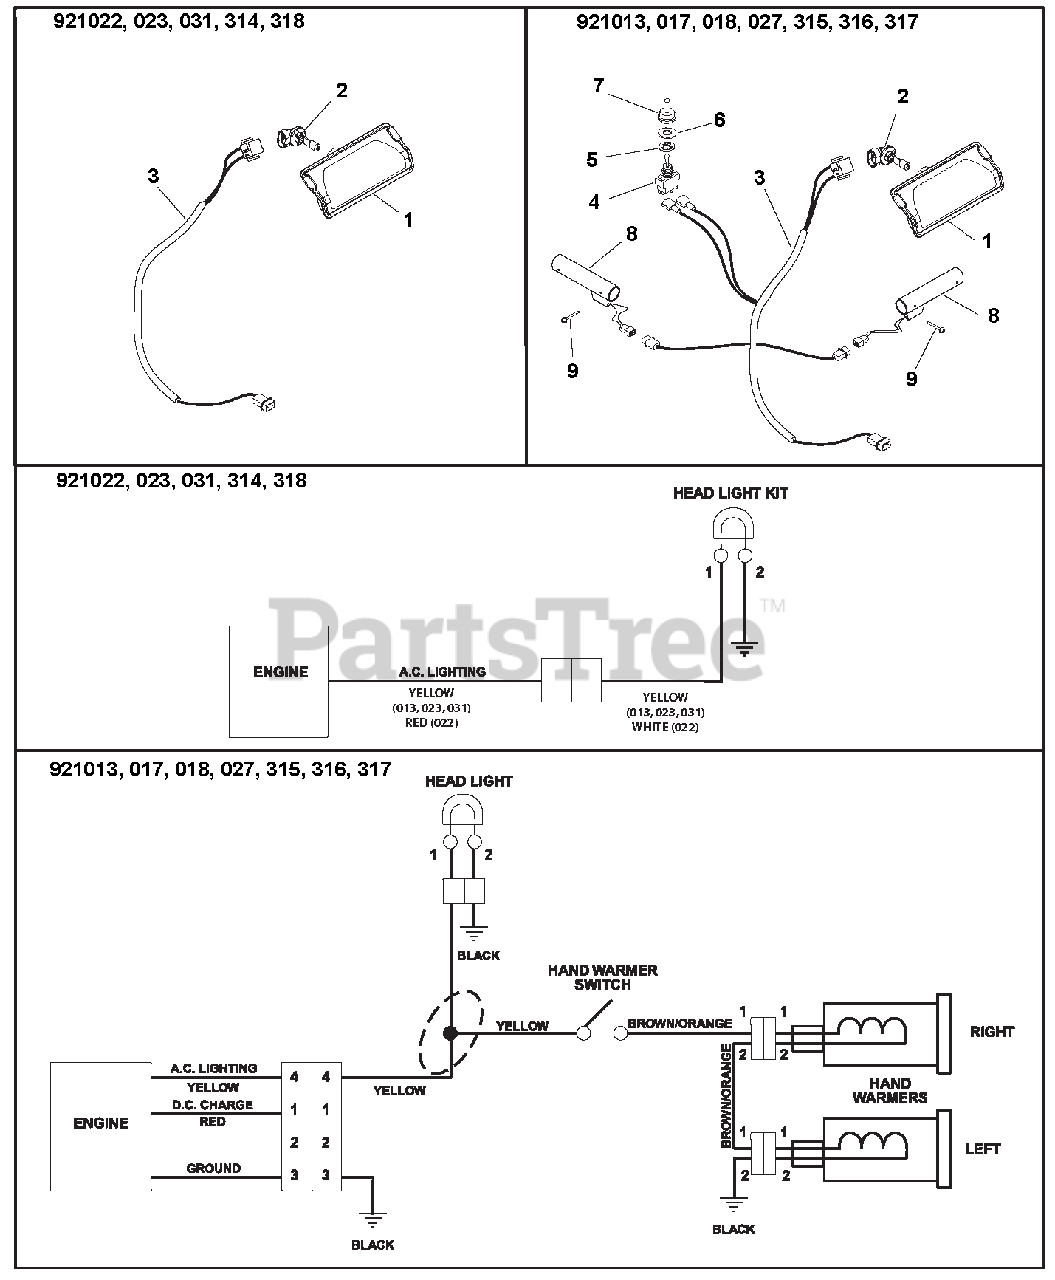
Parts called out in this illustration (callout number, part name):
1	HEADLIGHT ASSY, HALOGEN 20W
2	BULB, LIGHT-HALOGEN 20W
3	HARNESS, LIGHT & WARMER
3	HARNESS, LIGHT - DELUXE
4	SWITCH, ON/OFF
5	WSHR-LK-INT .563X.040 YWZC
6	WSHR-FL-STL .505X.875X.024 PL
7	BOOT, SWITCH
8	HEATED GRIP, MAGURA
9	RVT-POP #43 .125X.313 STL ZINC
